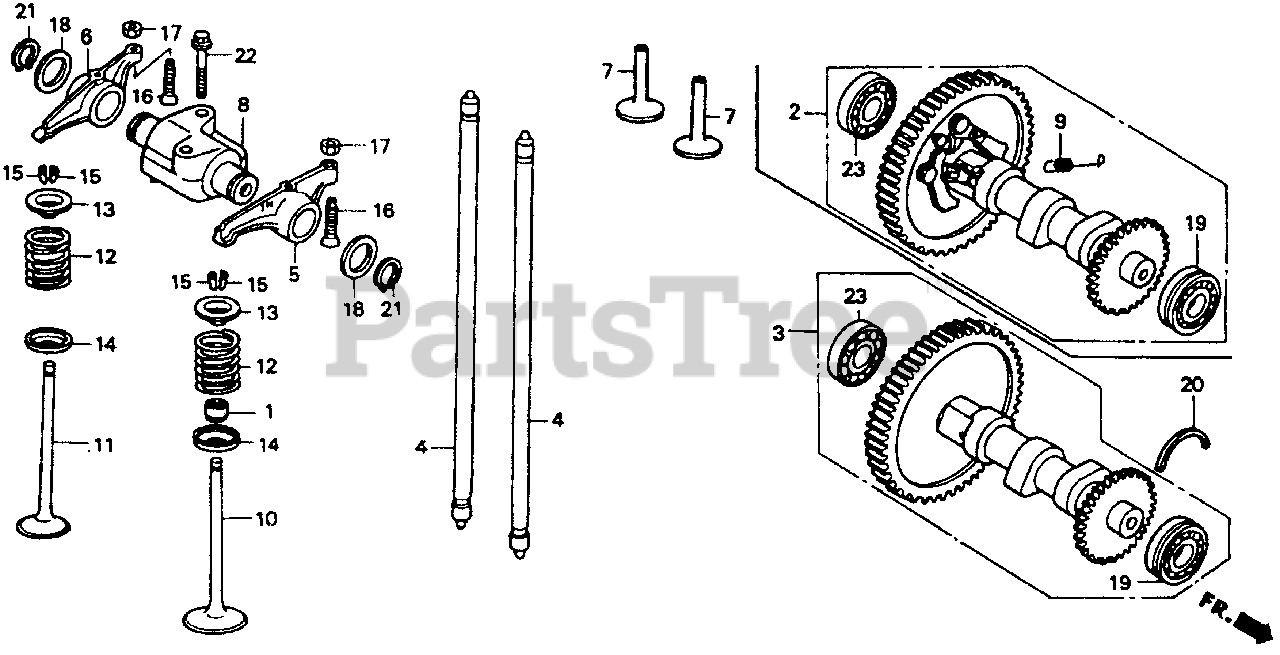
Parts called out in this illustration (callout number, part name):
1	SEAL A, VALVE STEM (ARAI)
2	CAMSHAFT ASSY. (USA)
4	ROD, PUSH
5	ARM, IN. VALVE ROCKER
6	ARM, EX. VALVE ROCKER
7	LIFTER, VALVE
8	SHAFT, ROCKER ARM
9	SPRING, WEIGHT RETURN
10	VALVE, IN.
11	VALVE, EX.
12	SPRING, VALVE
13	RETAINER, VALVE SPRING
14	SEAT, VALVE SPRING
15	COTTER, VALVE
16	SCREW, TAPPET ADJ.
17	NUT, TAPPET ADJ.
18	WASHER, THRUST (16MM)
19	BEARING A, SPECIAL BALL (6204) (NTN CORP.)
20	SET-RING (470)
21	CIRCLIP (OUTER) (16MM)
22	BOLT, FLANGE (6X35)
23	BEARING, RADIAL BALL (6204)
